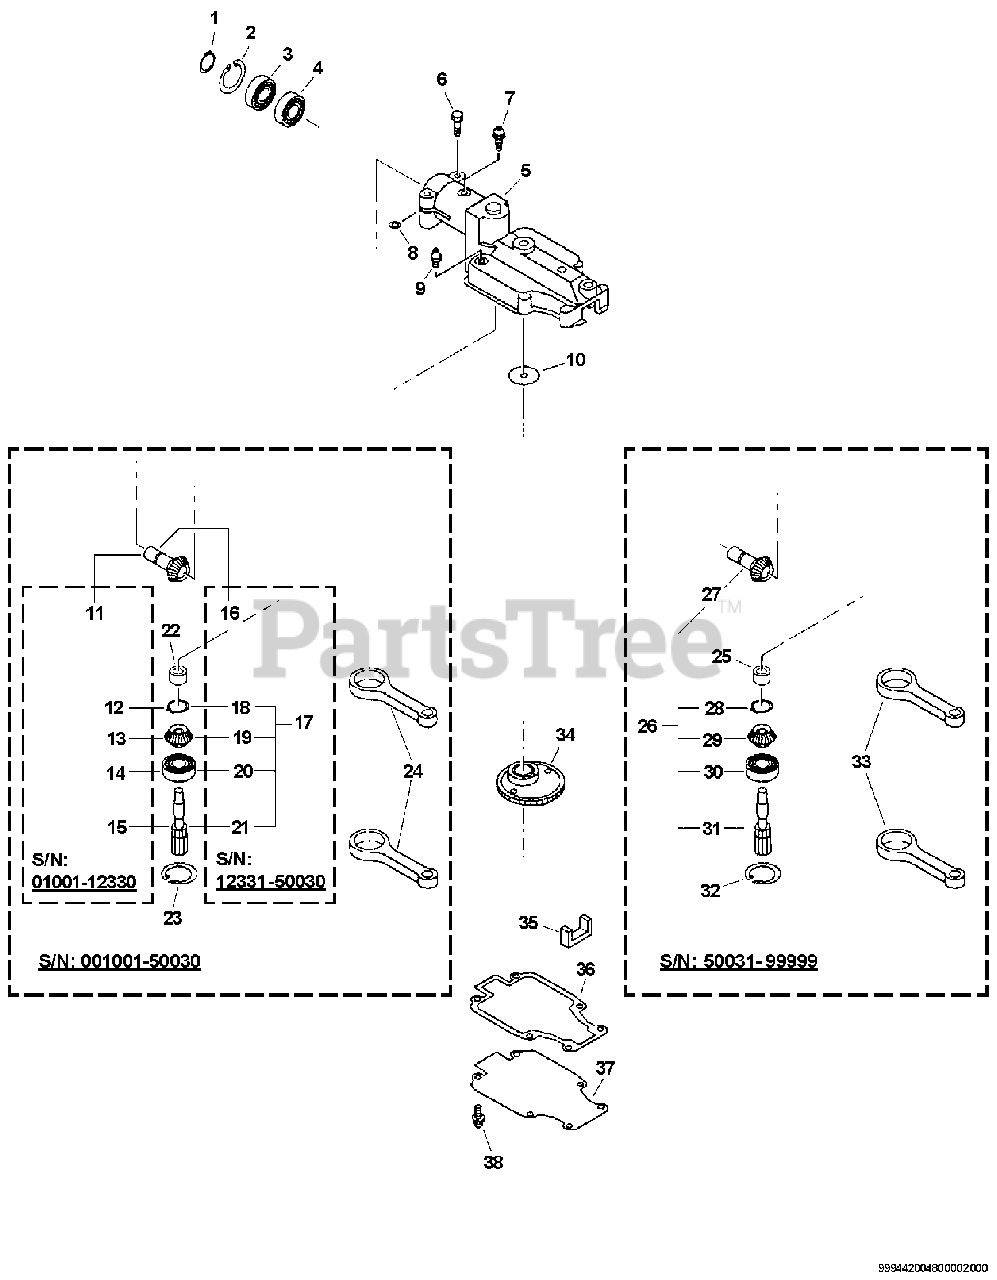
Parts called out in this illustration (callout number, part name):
1	RING, RETAINING - 12
2	RING, RETAINING - 24
3	BEARING, BALL - 6901
4	BEARING, BALL - 6901Z
5	CASE, GEAR
6	SCREW - 5X28
7	SCREW - 5X12
9	FITTING, GREASE
12	RING, RETAINING
13	GEAR - BEVEL -- DRIVEN
14	BEARING, BALL - 6901
15	GEAR - SHAFT
16	GEAR
17	SPUR GEAR ASSY
18	RING, RETAINING
19	GEAR - BEVEL -- DRIVEN
20	BEARING, BALL - 6901
21	GEAR - SHAFT
22	BEARING, NEEDLE
23	RING, RETAINING - 24
24	ROD, CONNECTING
25	BEARING, NEEDLE
26	SPUR GEAR SET
27	GEAR - BEVEL
28	RING, RETAINING
29	GEAR - BEVEL
30	BEARING, BALL - 6901
31	GEAR - SHAFT
32	RING, RETAINING - 24
33	ROD, CONNECTING
34	GEAR - DRIVE
35	SEAL, FELT
36	GASKET, GEAR CASE
37	LID, GEAR CASE
38	SCREW - 4X12
